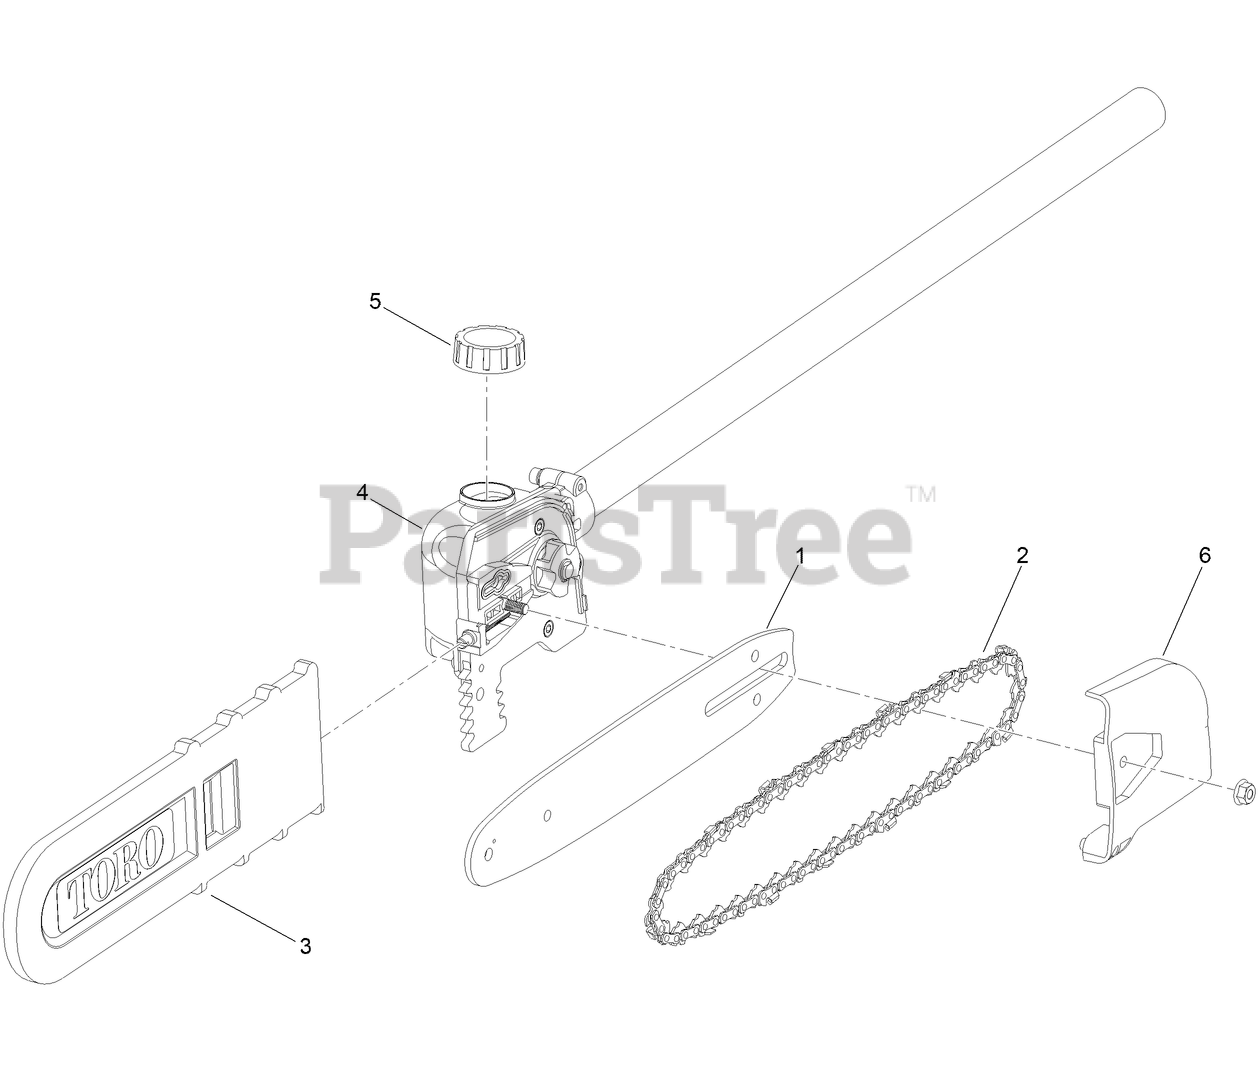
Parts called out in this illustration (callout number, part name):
2	CHAIN
3	SLEEVE-BAR
4	Head
5	OIL CAP
6	COVER-GEAR, DRIVER
